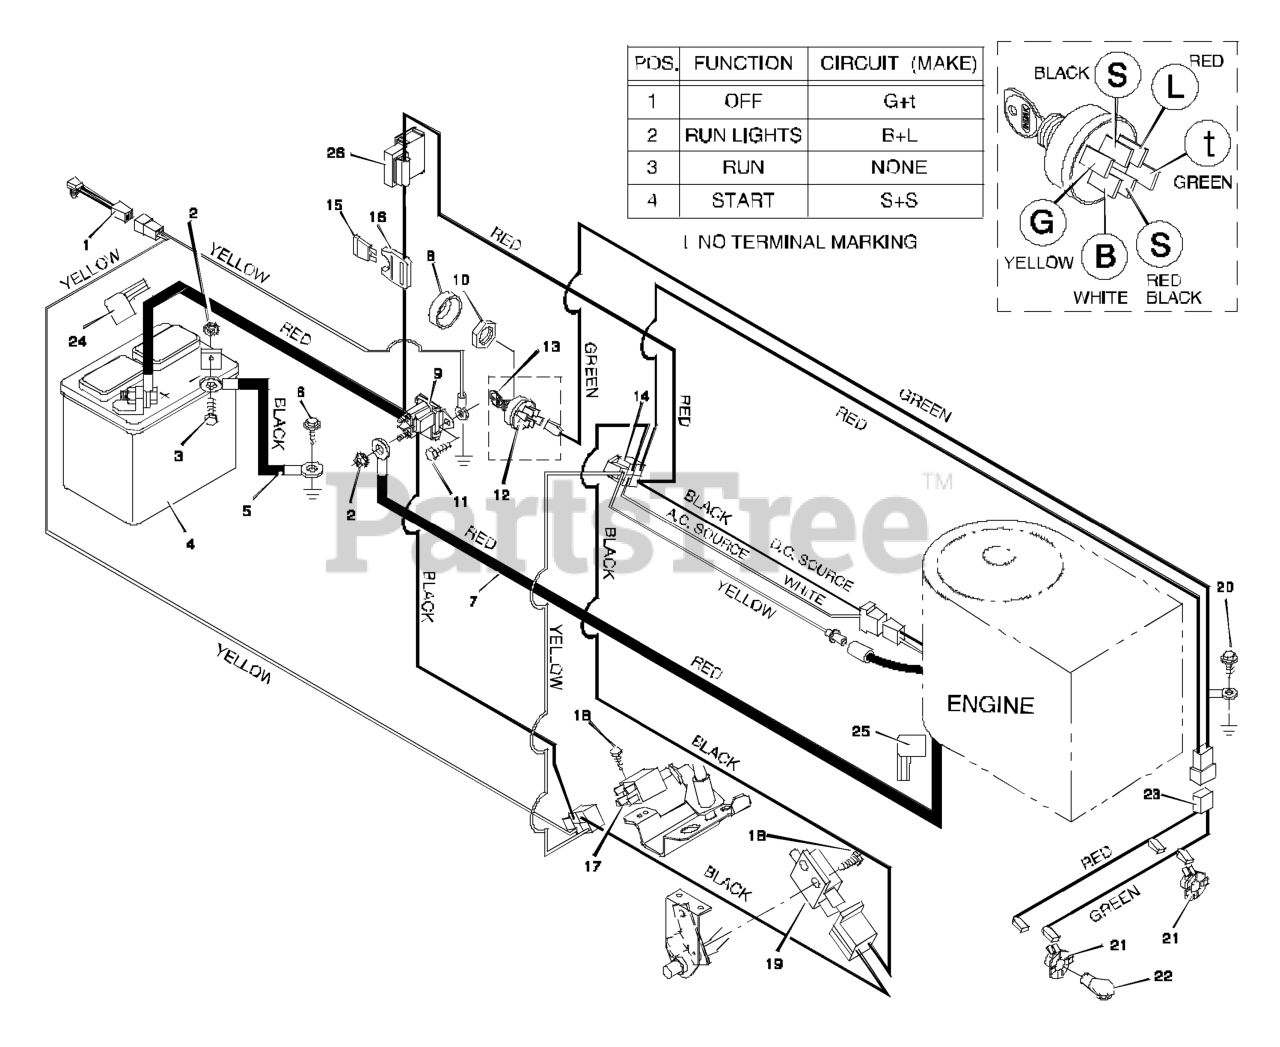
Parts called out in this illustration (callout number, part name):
1	Switch, Seat Sensor
2	Locknut
3	Bolt, Hex
4	Battery
5	Cable, Battery Ground
7	Cable, Red Battery
8	Cap, Ignition
9	Solenoid
10	Nut
12	Switch, Ignition
13	Key, Ignition
14	Harness, Chassis Wire
16	Holder, Fuse
17	Switch, Clutch
19	Switch, Clutch
20	Screw
21	Socket, Light
22	Bulb, Light
23	Harness, Light Wire
24	Cover, Terminal
25	Cover,
26	Ammeter
